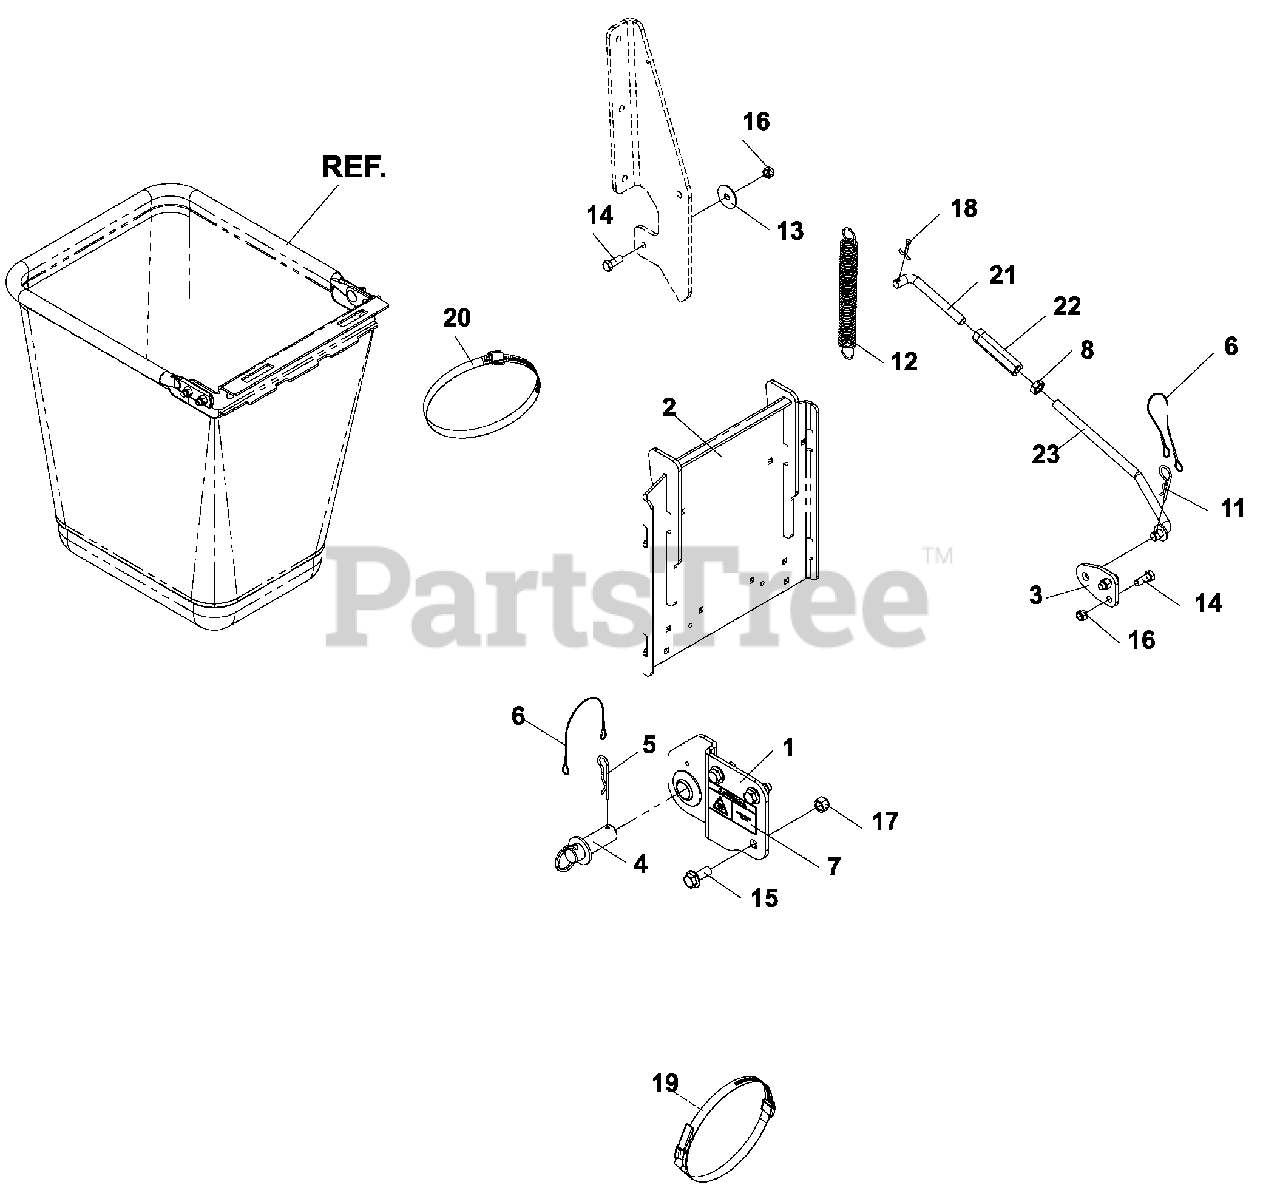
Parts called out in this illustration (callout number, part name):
1	HITCH BRACKET W/DECALS, RIGHT
2	REAR GUARD
3	SUPPORT BRACKET
7	DECAL, HOT SURFACE
8	NUT, 1/2-20, HEX JAM
11	HAIRPIN #4
13	FRICTION WASHER
14	HCS, 3/8-16 x 1, GR5
15	HFS, 1/2-13 X 1 1/2
16	NUT, 3/8C, NYLOC
17	NUT, 1/2C, NYLOC
18	COTTER PIN, 5/32 X 1 1/4
19	OVER CENTER BAND
20	HOSE CLAMP 6"-& 7"
21	SUPPORT LINKAGE, LH
22	TURNBUCKLE, 1/2"
23	SUPPORT LINKAGE
